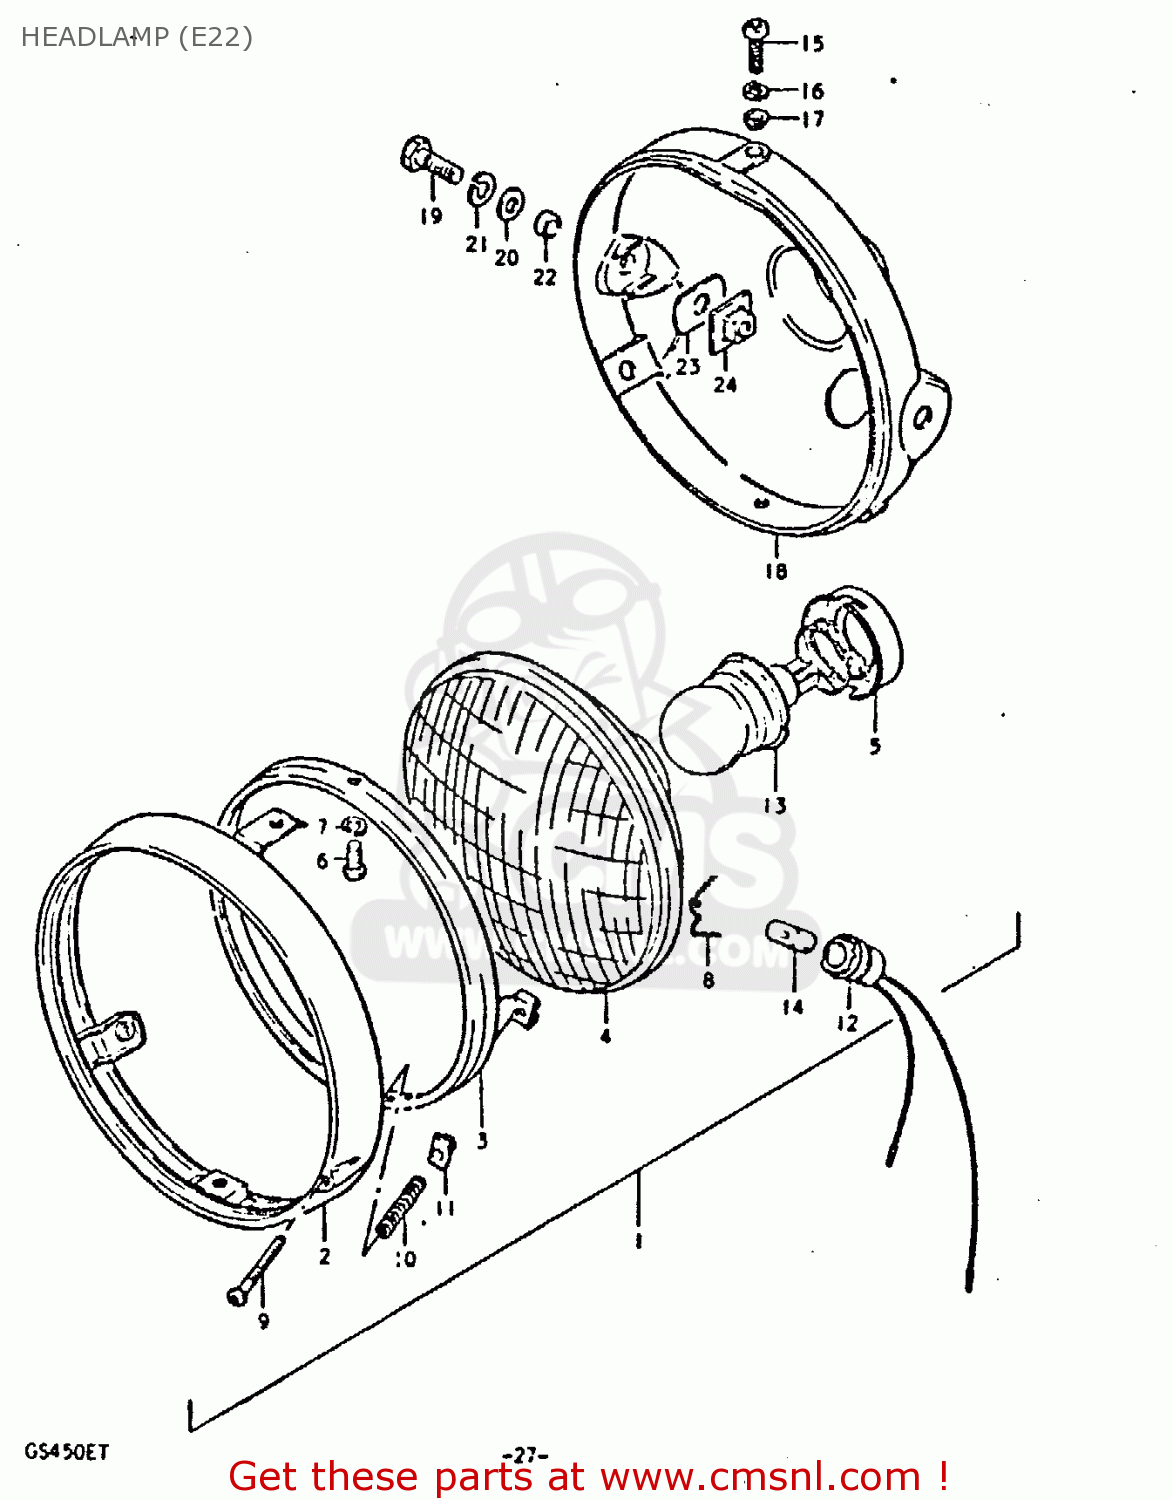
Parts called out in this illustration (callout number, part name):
1	HEADLAMP ASSY
2	RIM,HEADLAMP
3	RETAINER,HEADLAMP
4	UNIT
5	SETTER,BULB
6	SCREW
7	LOCK WASHER
8	SPRING
9	SCREW,HEADLAMP ADJUST
10	SPRING
11	NUT
12	SOCKET
13	BULB(12V45/40W)
14	BULB(12V4W)
15	SCREW
16	WASHER,LOCK
17	WASHER
18	HOUSING,HEADLAMP(BLACK)
19	BOLT
20	WASHER
21	LOCK WASHER
22	SPACER (8.8X12X7)
23	CUSHION
24	PLATE,HEADLAMP HOUSING
